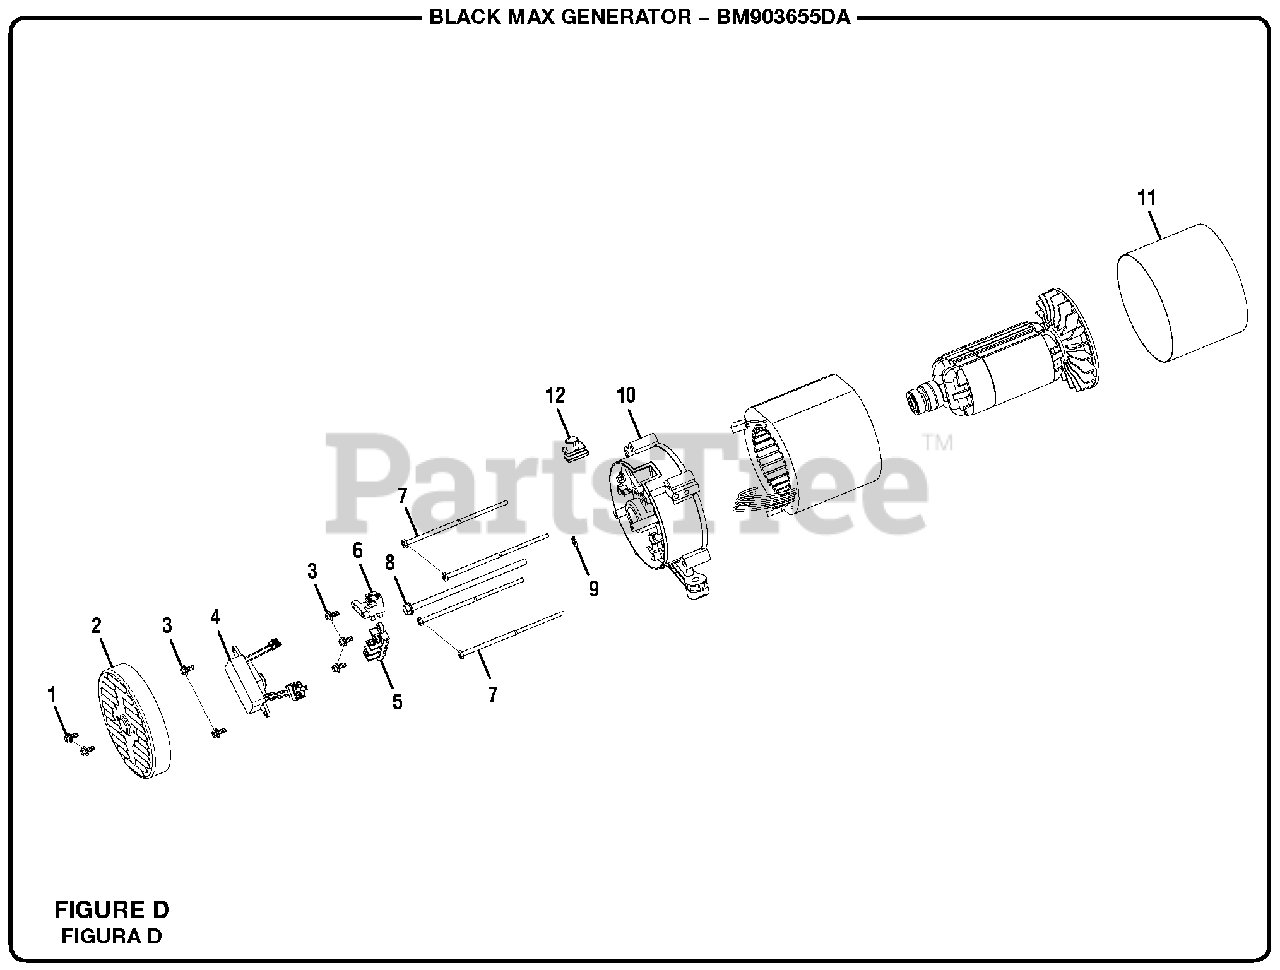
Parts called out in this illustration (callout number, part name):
1	Bolt (M5 x 12 mm, Hex Hd.)
2	Brush Cover
3	Bolt (M5 x 16 mm, Hex Hd.)
4	Automatic Voltage Regulator
5	Terminal Block
6	Brush Assembly
7	Stator Bolt
8	Rotor Bolt
9	Lock Washer (5/16 in.)
10	Bearing Support
12	Rubber Boot
